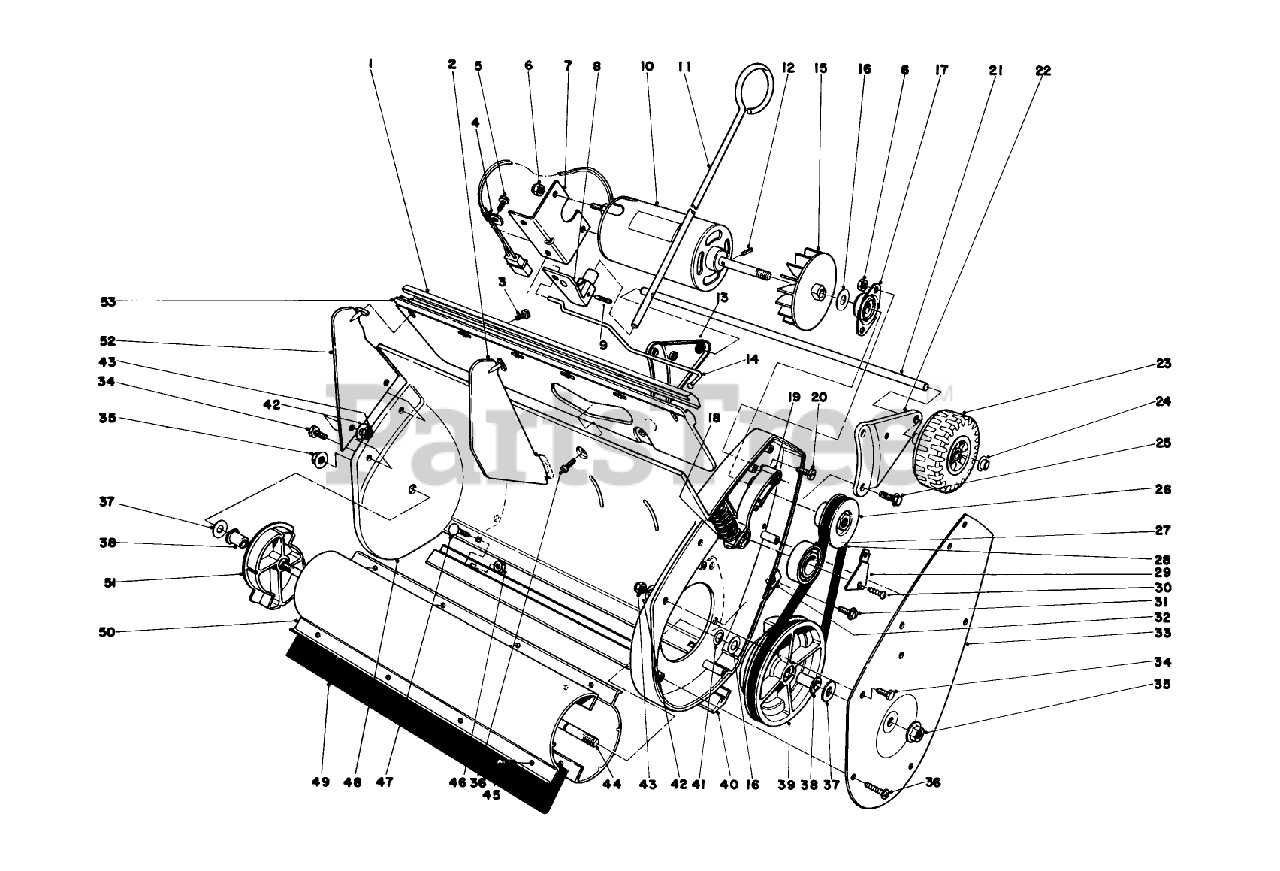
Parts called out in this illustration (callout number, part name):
1	MOULDING
2	VANE INNER
3	10-16 X 3/8 THDG SCREW
4	CLIP-CLOSED, INSULATED
6	NUT-LOCK, NI
7	MOUNTING BRKT B
8	VANE ADJ BRKT
9	GROOVE PIN
10	Motor
11	VANE ADJ ROD
12	SPRING PIN
13	Bracket R.H.
14	Linkage Vane Adjustment
16	WASHER-THRUST
17	SIDE FLANGE BRG
18	IDLER COMP. SPRING
19	IDLER ARM
20	Screw
21	AXLE SHAFT
22	Wheel Bracket L.H.
23	S-120 WHEEL
24	PUSHNUT-CAP, WASHER
25	Screw
26	DRIVE PULLEY
27	BEARING-BALL
29	IDLER PULLEY RETAINER
30	#8 X .625" PHILPS PAN H
31	SCREW-HWHTF
32	NUT-TYPE J
33	Cover-Belt Case
34	SCREW-HWH
35	NUT-HF
36	Screw
37	THRUST WASHER (THICK)
38	BUSHING ROTOR
39	Pulley-Driven
40	SCRAPER-SERVICE
41	RING-RETAINING
42	Washer
43	NUT-LOCK, NI
44	ROTOR SHAFT
45	Screw
46	NUT-KEPS
47	SCREW-CARR
48	Housing
49	Blade-Rotor
50	ROTOR
51	END CAP ROTOR
52	VANE OUTSIDE
53	Vane Mount
